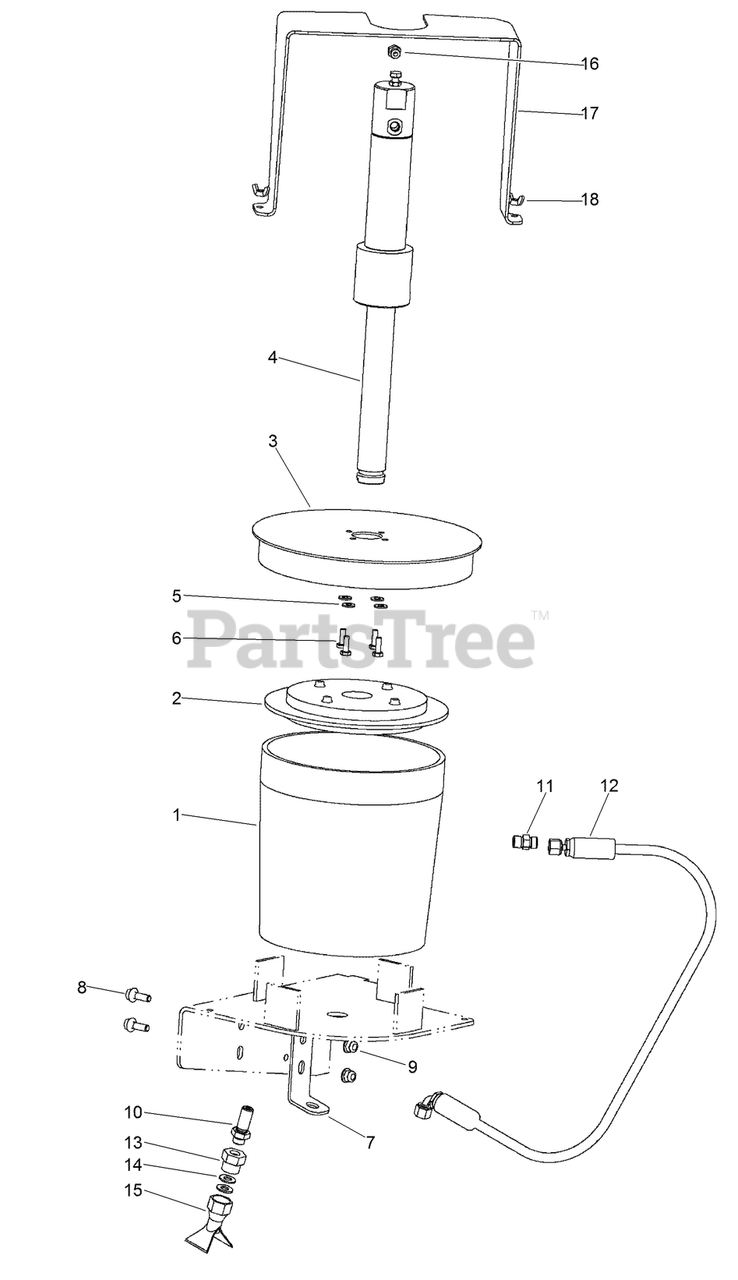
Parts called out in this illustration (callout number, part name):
1	COMPOUND-THREAD
2	SEAL - Rubber, Follower
3	WELDMENT - Cover
4	HYD GREASE PUMP ASM
5	WASHER-FLAT
6	BOLT - Hex Hd .250 x .750 GR8 PHC
7	BRACKET - Nozzle, Greaser
8	SCREW-HH
9	NUT-TORQUE, PREVAILING
10	CONNECTION - Bulkhead, Straight -4 ORFS / -4 ORB
11	CONNECTION - Straight, -4 ORFS / -6 ORB
12	HOSE-HYD
13	REDUCER-STRAIGHT, THREADED
14	WASHER - 0.406 x 0.812 x 0.065 in HDN ZND
15	NOZZLE - Spray, Airless
16	PLUG - Hex, ORB 1/4
17	TIE DOWN - Grease Cover
18	NUT - Wing, 1/4 - 20 UNC ZND
